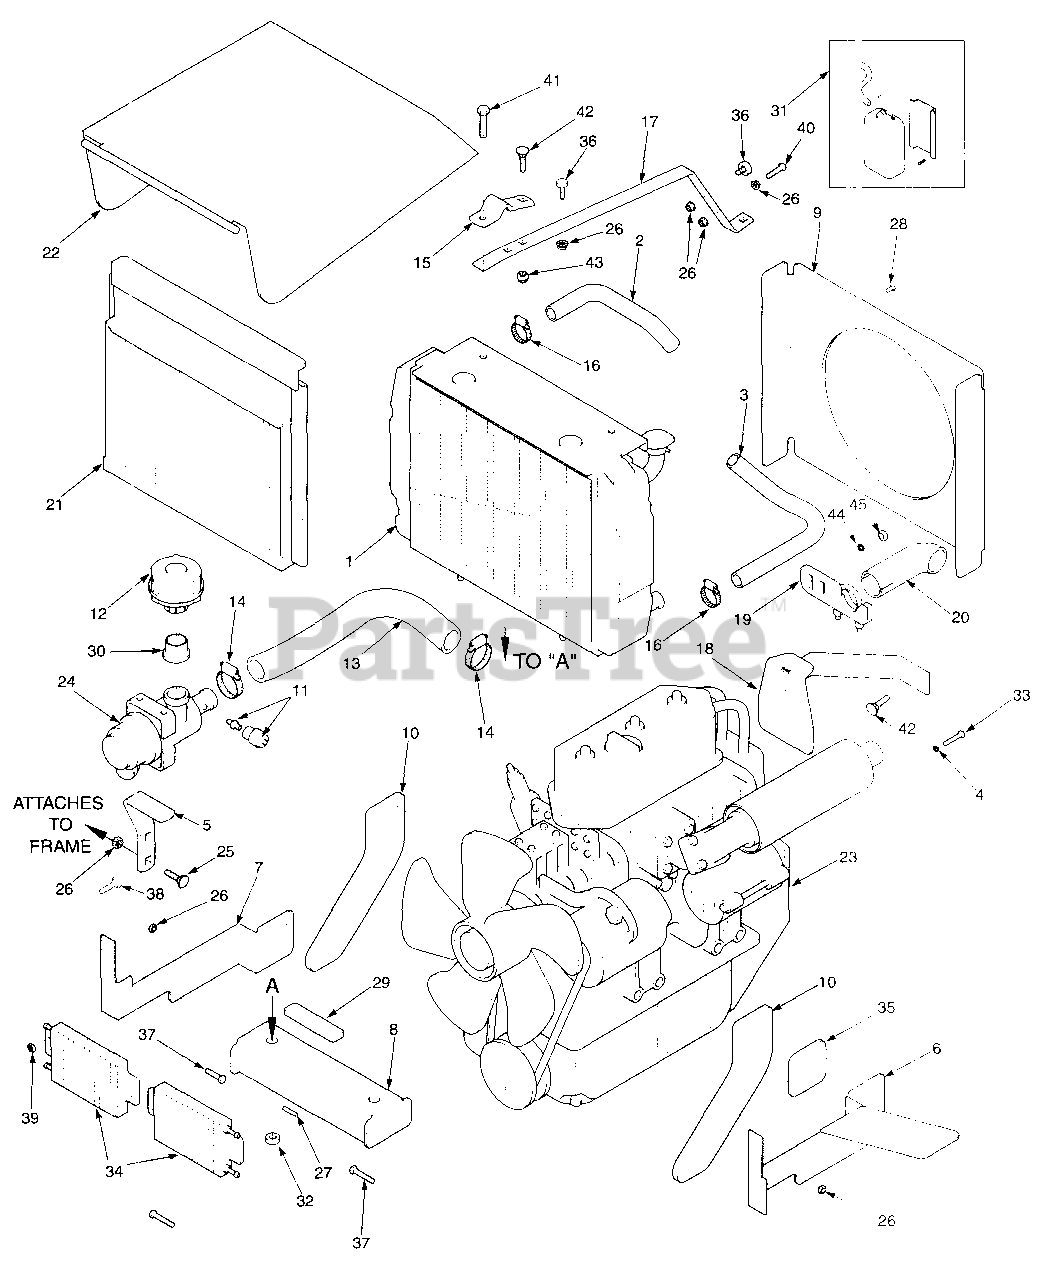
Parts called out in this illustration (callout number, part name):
1	Radiator
2	Hose, Upper Radiator
3	Hose, Lower Radiator
4	Lockwasher, 5/16 (.317 x .586 x .078) Helical Spring
5	Bracket, Air Cleaner
6	Bracket, Engine Mounting LH
7	Bracket, Engine Mounting RH
8	Bracket, Radiator Mounting
9	Shroud, Radiator
10	Plate, Engine Mounting
11	Indicator, Air Cleaner
12	Pre-Cleaner, Engine Air
13	Hose, Air Intake
14	Clamp, Hose (2.25" Dia.)
15	Hinge, Hood
16	Clamp, Hose (1.50" Dia.)
17	Bracket, Hood Support
18	Bracket, Exhaust Support
19	Clamp Weldment, Muffler
20	Elbow, Exhaust
21	Screen, Debris
23	Engine, Briggs & Stratton 31 HP
24	Air Cleaner Assembly w/ Mounting Band
25	Bolt, Carr. 5/16-18 x .75"
26	Nut Serr. Flng 5/16-18
27	Pin Rue Cotter 1/2" dia.
28	Rivet, Pop 1/8 x .294"
29	Pad. Radiator
30	Adaptor, Pre-Cleaner
31	Coolant Tank Assembly w/Hose
32	Spacer, Radiator
33	Bolt Hex Head M8 x 20MM LG
34	Cooler, Oil
35	Engine Spacer
36	Bumper Rubber
37	Bolt Hex Head 5/16-18 x .75"
38	Bolt Carriage 1/4-20 x .50"
39	Nut, 1/4-20 Serrated Flange
40	Bolt Hex Head 5/16-18 x 1.50"
41	Bolt Hex Head 5/16-18 x .75 Serrated Flange
42	Bolt Carriage 5/16-18 x 1.0"
43	Nut, 5/16-18 Elastic Stop
44	Flatwasher, 5/16 (.375 x .875 x .083)
45	Nut, 5/16-18 Elastic Stop
